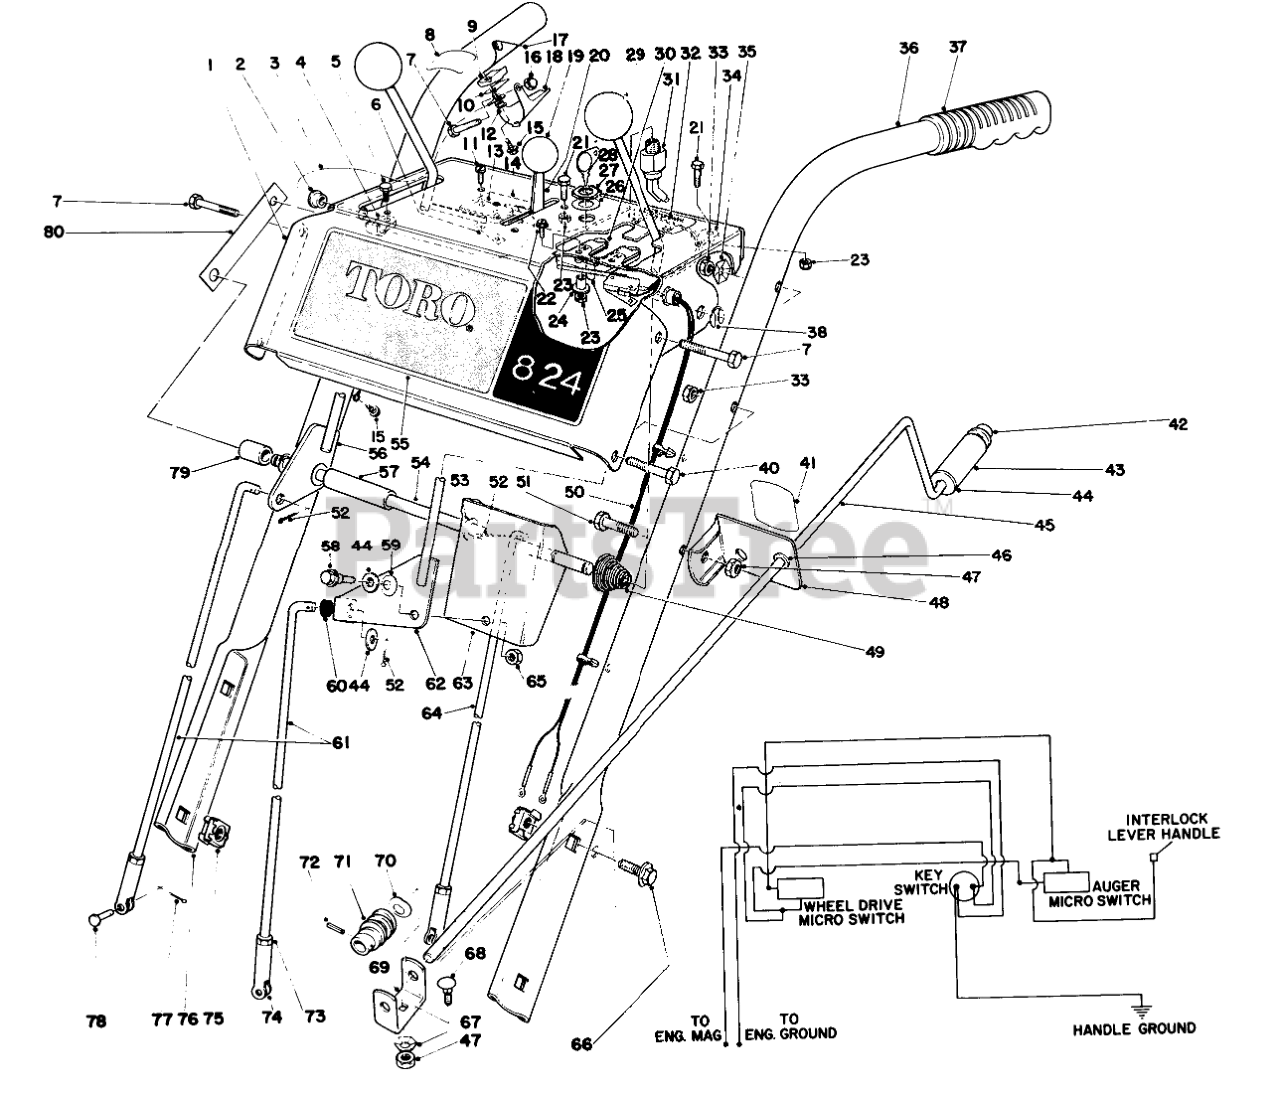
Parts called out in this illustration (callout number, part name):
1	Escutcheon
2	Snap Bushing
3	Wire Assembly
4	PLASTIC CLIP
5	SCREW
6	NUT-SPEED
7	SCREW-HH
8	INTERLOCK DECAL
9	Insulator
10	INTERLOCK CONTACT
11	SCREW-SPH
12	WASHER INSULATOR
13	MICRO SWITCH
14	SWITCH MTG PAD
15	SCREW
16	NUT-CAP
17	INTERLOCK SPRING
18	SAFETY INTRLOCK LEVER
19	CONTROL KNOB
20	THROTTLE CONTROL
21	HEX HEAD SEMS 10-24X1/2
22	SCREW-SRH
23	Nut
24	INTERLOCK SPACER
25	INTERLOCK SPRING
26	WASHER-TOOTH, INTERNAL
27	NUT-HH
28	Key
30	Slide Interlock
31	SWITCH-ON / OFF
32	INSTR DECAL
33	NUT-LOCK, CONE
34	CABLE CLAMP
35	Washer
36	LEFT HANDLE
37	Grip Handle
38	RING-CLIP
40	SCREW-HH
41	CHUTE DECAL
42	RETAINER-PUSH ON
43	CHUTE CONTROL GRIP
44	WASHER-FLAT
45	CHUTE CONTROL ROD
46	Bushing
47	NUT-LOCK, NI
48	Chute Control Rod Mounting (Incl. Ref. #41 & 46)
49	CONICAL SPRING
50	Wire Harness Interlock
51	SCREW-HH
52	PIN-COTTER
53	WASHER-FLAT
54	PIVOT ROD
55	ESCUTCHEON DECAL
56	LEVER WA
57	SHIFT LEVER SPACER
58	SHOULDER SCREW
59	7/16 SPRING WASHER
60	GROMMET-RUBBER
61	SPEED SELECTOR ROD
62	SHIFT LEVER WA
63	SHIFT BRACKET
64	TRACTION CONTROL ROD
65	NUT-LOCK, CONE
66	SCREW-HHF
67	WASHER-LOCK
68	BOLT-CARR
69	WORM BRACKET
70	WASHER-SPRING
71	GEAR-WORM, CHUTE
72	PIN-SPRING
73	NUT-HJ
74	CLEVIS
75	Retained Nut
76	RIGHT HANDLE
77	PIN-COTTER
78	PIN-CLEVIS
79	AUGER LEVER SPACER
80	ESCUTCHEON SUPT STRAP
